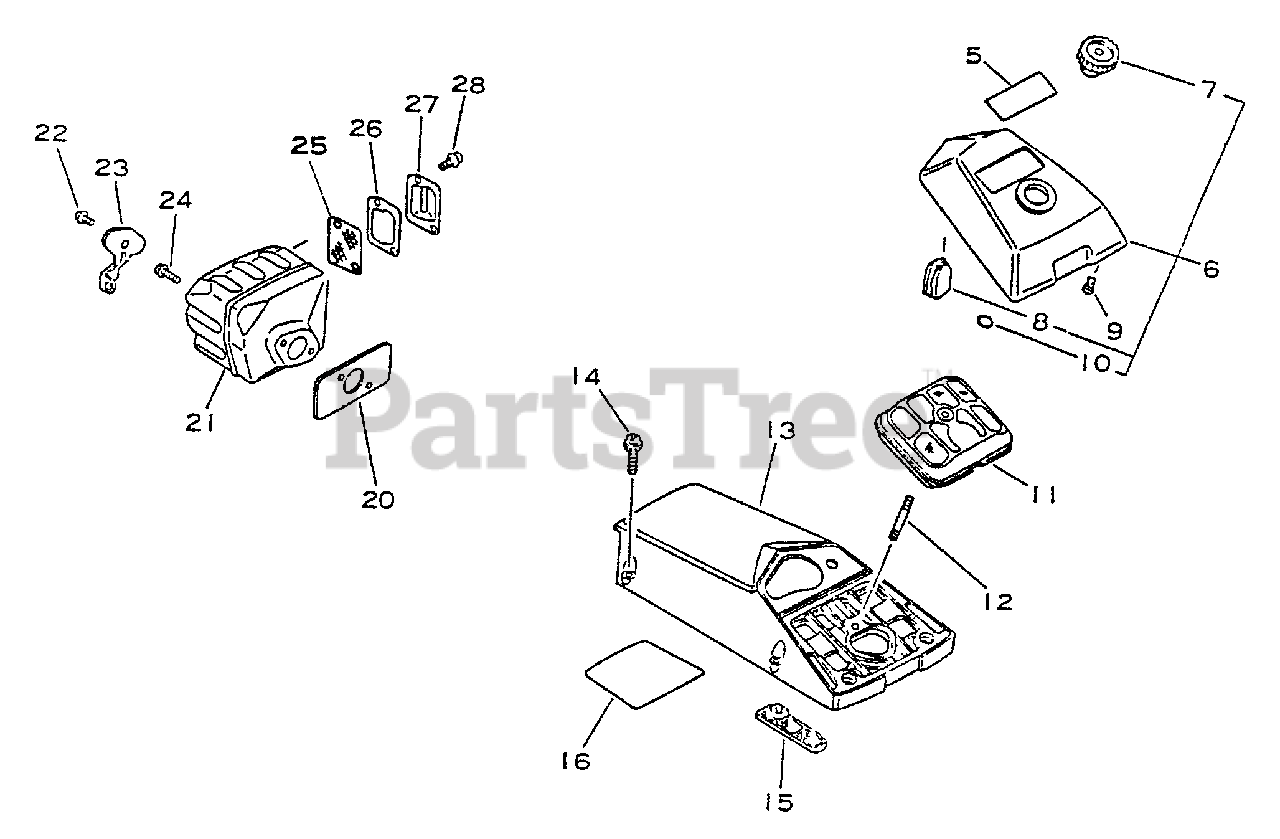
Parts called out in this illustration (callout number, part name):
5	LABEL - MODEL
6	COVER, AIR FILTER
7	THUMBNUT
10	O-RING - 11
11	FILTER, AIR
13	COVER, ENGINE
14	SCREW - 5X20
15	FILTER, AIR
16	COVER, ENGINE
20	GASKET, EXHAUST
21	MUFFLER
22	SCREW - 5X10
23	BRACKET, MUFFLER
24	SCREW - 5X20
25	SCREEN, SPARK ARRESTOR
26	GASKET, EXHAUST
27	LID, MUFFLER
28	SCREW - 4X8
